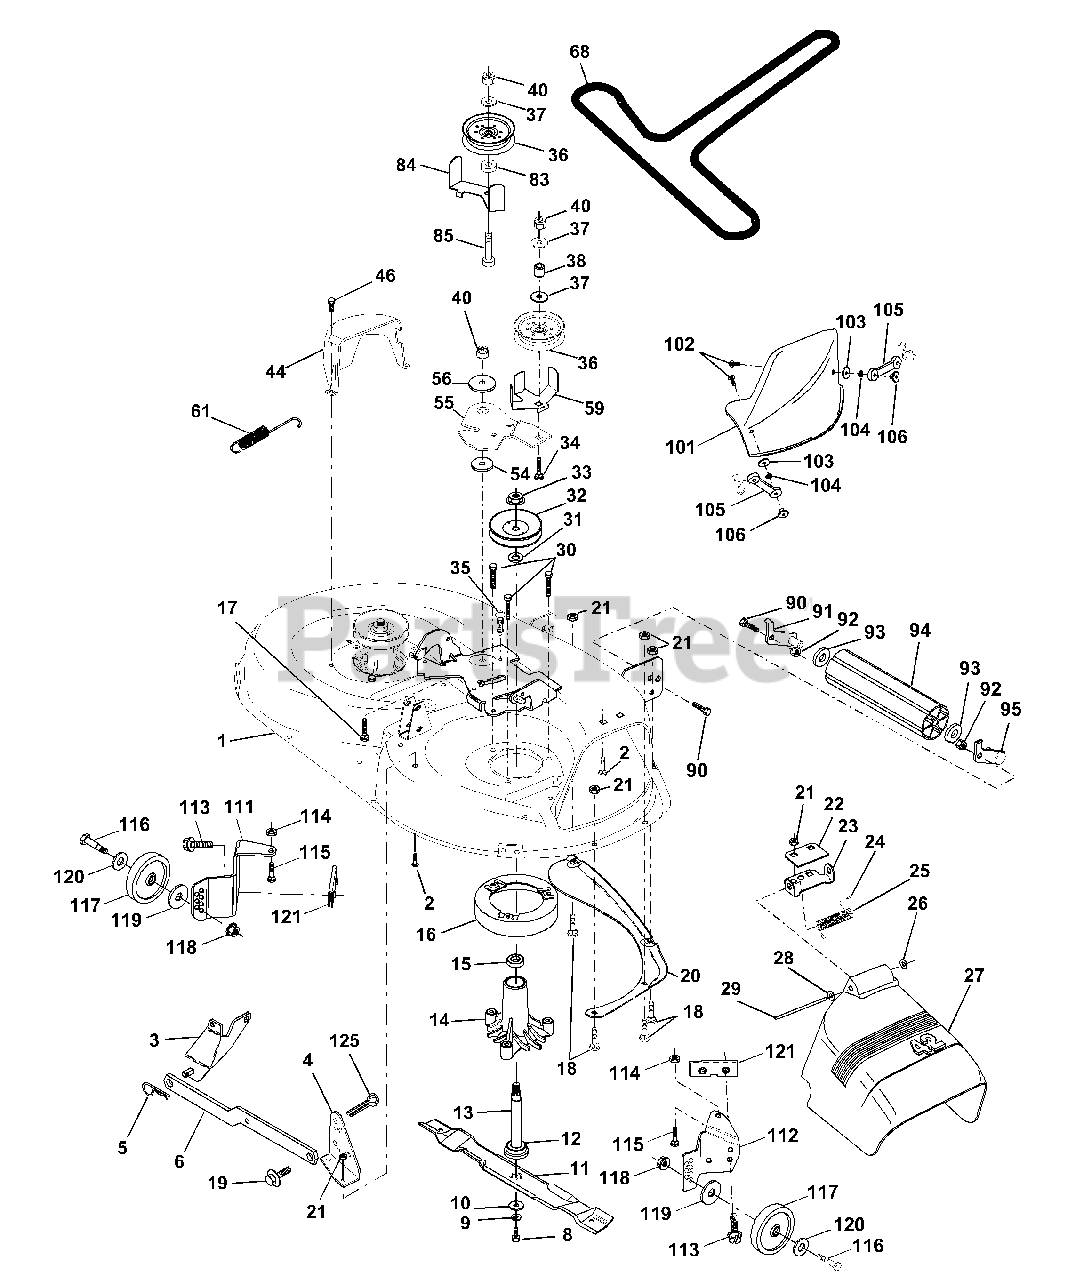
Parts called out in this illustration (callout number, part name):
1	Housing Asm Mower 42"94 T-Path
2	Bolt Rdhd Sqnk 5/16-18unc X3/4
3	Bracket Asm Fr Sway Bar 38/42
4	Bracket Asm Deck 42"sway Bar
5	Retainer Spring
6	Arm Suspension Rear
8	Bolt 3/8-24x1 25 Gr8 Patched
9	Washer Lock Hvy 3/8 Unplated
10	Washer Hard Blade Mower Vented
11	Blade Mower Mulching 42"
12	Bearing Ball #6204 (Mandrel)
13	Shaft Asm W/lower Bearing
14	Housing Mandrel Vented(machd)
15	Bearing Ball Mandrel
16	Stripper Round Mower
17	Bolt Rdhd Sqnk 3/8-16 X 2-1/4
18	Bolt Carr 5/16-18 X 5/8
19	Bolt Shoulder
20	Baffle Vortex 42
21	Nut Crown Lock 5/16-18
22	Stiffener Bracket 42"deck
23	Bracket Deflector Mower 42"
24	Cap Sleeve 80x 112 Blk Mower
25	Spring Torsion Deflector 2 52
26	Nut Push Phos & Oil
27	Shield Deflector Mower 42" Blk
28	Washer 11/32 X 5/8 X 16 Ga
29	Rod Hinge 42"6 75 Wlg
30	Screw Thdrol Hex Hd Zinc Mwr.
31	Washer Spacer Mower Vented
32	Pulley Mandrel 42"
33	Nut 9/16top Lock Flng Cntr
34	Bolt RDHD 3/8-16 UNC x 2-3/4 G r.5
35	Fastener Christmas Tree
36	Pulley Idler Flat 3 060
37	Washer 13/32 X 13/16 X 16 Ga
38	Spacer Spring Stop Idler
40	Nut Lock 3/8-16 Unc
44	Guard Mandrel LH Black
46	Screw Thdrol 1/4-20x5/8
54	Washer Hardened
55	Arm Idler 42"mower LT/YT
56	Spacer Retainer Pm Mower
59	Guard, Belt
61	Spring Ext. Elect
68	V-Belt Mower
83	Washer Sintered
84	Keeper Belt Idler Fixed
85	Bolt Carriage 3/8-16 x 2-1/4 Gr.5
90	Bolt Fin Hex 3/8-16unc X 1
91	Bracket Asm Noseroller LH
92	Nut Lock Hex w/ins. 3/8-16 UNC
93	Washer 17/32 X 7/8 X 16 Ga
94	Roller Nose 38 & 42
95	Bracket Asm Noseroller RH
101	Cover Mulching 42" Blk
102	Screw
103	Washer #10
104	Washer Lock #10
105	Latch Asm Bagger
106	Nut Weld .327/.304 #10-24
111	Bracket Wheel Gauge Lh 42" Deck
112	Bracket Gauge Wheel Rh 42" Deck
113	Screw Thdrol 5/16-18 x 3/4 TYT
114	Nut Keps 5/16 - 18 UNC
115	Bolt Carriage 5/16 - Unc x 1/2
116	Bolt Shld "A" 2.41 "B" 1.66
117	Wheel Gauge blk. 4.93
118	Nut Centerlock 3/8 - 16 UNC
119	Washer 3/8 x 7/8 x 14 Ga.
120	Washer 17/32 x 15/16 x 12 Ga.
125	Cotter Pin
